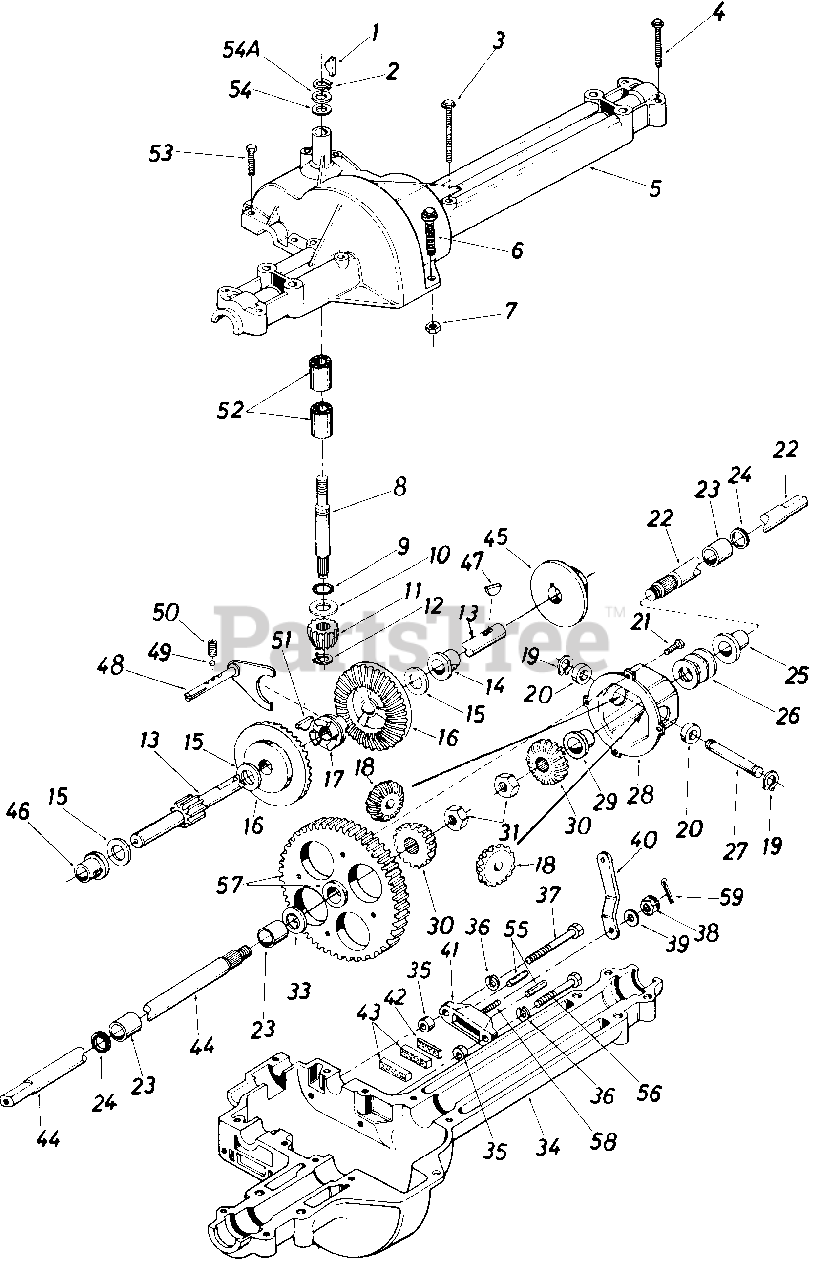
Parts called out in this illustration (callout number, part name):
1	#4 Hi-Pro Key 3/32 x 5/8" Dia.
2	Snap Ring .625" Shaft
3	Hex Bolt 1/4-20 x 1.75" Lg.
4	Hex Bolt 1/4-20 x 1.25" Lg.
5	Upper Housing
6	Hex Fl-Bolt 1/4-20 x .88" Lg.
7	Hex Nut 1/4-20 Thd.
8	Input Shaft
9	Square Seal 5/8" I.D.
10	Thrust Washer 5/8" I.D. x 1.25" O.D.
11	Pinion Input 14T
12	Retaining Ring 7/16" Ext.
13	Drive Shaft-R.H.
14	Flange Brg. 5/8" I.D. x 3/4" Lg.*
15	Fl-Wash.
16	Bevel Gear 42T
17	Clutch Collar
18	Miter Gear 15T
19	Snap Ring
20	Thrust Bearing 1/2" I.D. x 1.0"O.D.
21	Pan Head Scr. 1/4-20 x .50" Lg. wlPatch
22	Axle R.H.
23	Sleeve Bearing 3/4" I.D. x 1.0" Lg.
24	Oil Seal 3/4" I.D.
25	Flange Bearing 3/4" I.D. x 15/16" Lg.
26	Fl-Wash. .760" I.D. x 1.49"O.D.
27	Cross Shaft
28	Differential Housing Ass'y.
30	Miter Gear
31	Hex Ins. L-Nut 1/2-20 Thd.
33	Fl-Wash. .760" I.D. x 1.49" O.D.
34	Lower Housing
35	Spacer .53" O.D. x 3/8" Lg.
36	L-Wash. 1/4" I.D.*
37	Hex Bolt 1/4-20 x 1.50" Lg. (Grade 5)
38	Castle Nut 5/16-24 Thd.
39	Fl-Wash. .344" I.D. x .875"O.D.
40	Actuating Arm-R.H.
41	Brake Yoke
42	Puck Plate
43	Brake Puck
44	Axle L.H.
45	Brake Disc
46	Flange Bearing 5/8" I.D. x 15/16" Lg.
47	Woodruff Key 3/16 x 5/8 HT
48	Shift Fork Ass'y.
49	Ball Detent.250" Dia.
50	Spring Detent
51	#9 Hi-Pro Key 3/16" x 3/4" Dia. HT
52	Needle Brg. 5/8" I.D. x 1/2" Lg.
53	Hex Bolt 1/4-20 x 1.00" Lg.
54	Fl-Wash. 5/8" I.D. x .030
54A	Fl-Wash. 5/8" I.D. x .040
55	Actuating Pin 5/16" Dia.
56	Hex Bolt 1/4-20 x 1.50" Lg. (Grade 5)
57	Differential Gear 72T Ass'y. w/ Bearing
58	Sq. Hd. Bolt 5/16-24 Thd.
59	Cotter Pin 3/32" Dia. x .50" Lg.
